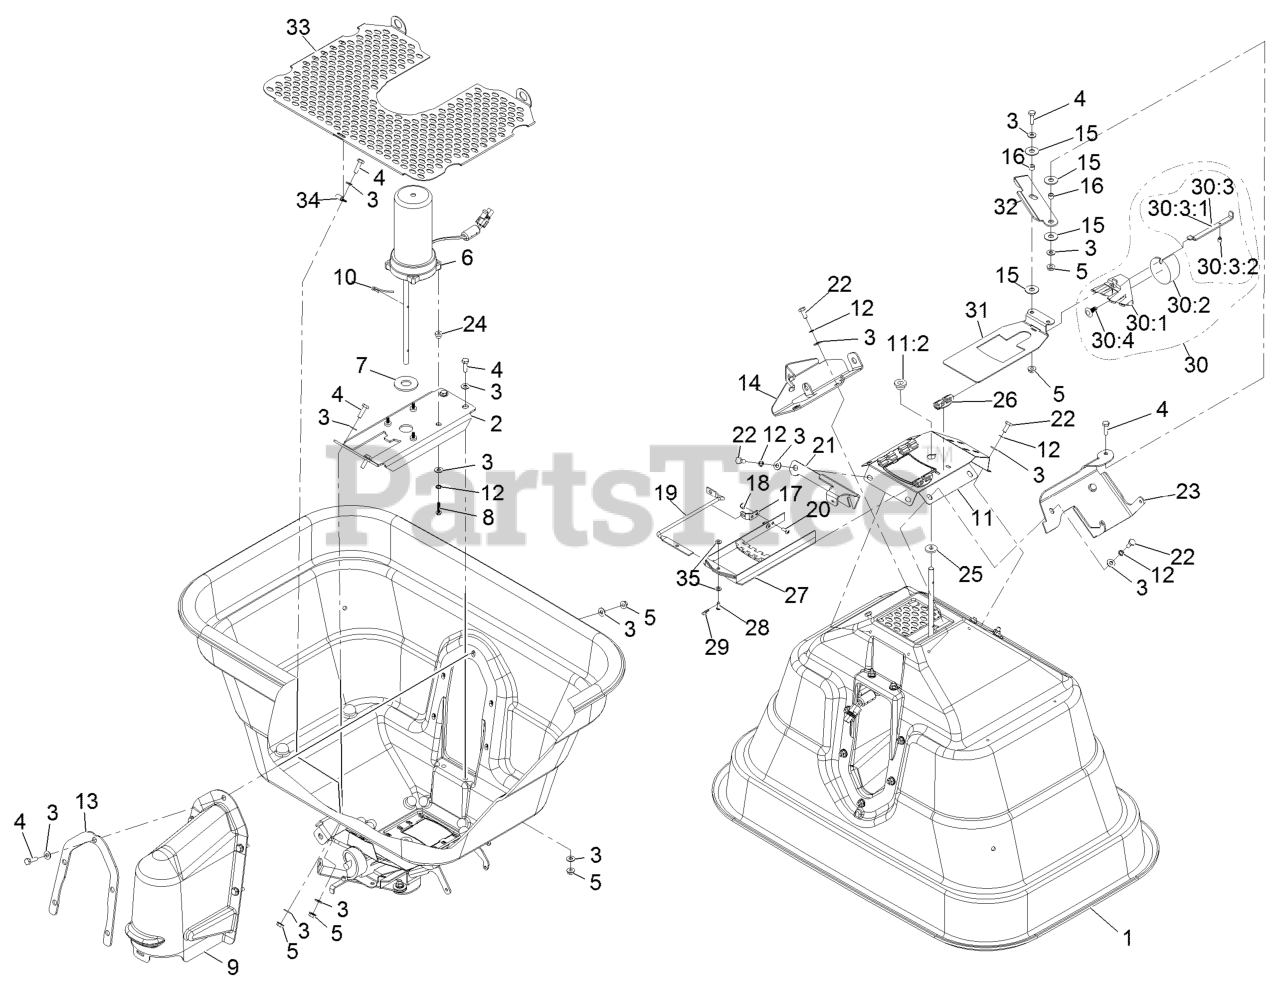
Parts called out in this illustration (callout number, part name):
2	BRACKET-MOUNT, MOTOR
3	WASHER-FLAT
4	SCREW-HH
6	SPREADER MOTOR ASM
8	SCREW-SHWH
9	COVER-MOTOR
10	AGITATOR
11	MULCH PLATE W/ BEARING AS
11:2	BEARING-BOTTOM, HOPPER
12	WASHER-LOCK, INT
13	FLANGE-COVER, MOTOR
14	BRACKET-HOPPER, GATE CONT
17	BRACKET-DIFFUSER
18	NUT-HEX
19	ROD-CONTROL, DIFFUSER
20	SCREW-PPH
21	BRACKET-SPRING, HOPPER DE
22	SCREW-HH
23	BRACKET-LEVER, HOPPER GAT
25	WASHER-FELT
26	GUIDE-RATE, GATE
27	DIFFUSER
28	PIN-CLEVIS
29	PIN-COTTER, HAIR
30	RATE DIAL ASM
30:1	MOUNT-DIAL
30:2	DIAL
30:3	Rate Gate Link ASM
30:3:1	LINK-GATE, RATE
30:3:2	SCREW-SHOULDER, SLOTTED
30:4	CLIP
31	GATE-RATE
32	LEVER-GATE
33	SCREEN-HOPPER, LARGE HOLE
33	SCREEN-HOPPER, MEDIUM HOL
33	SCREEN-HOPPER, SMALL HOLE
34	CLAMP-LOOP
35	WASHER-FLAT
